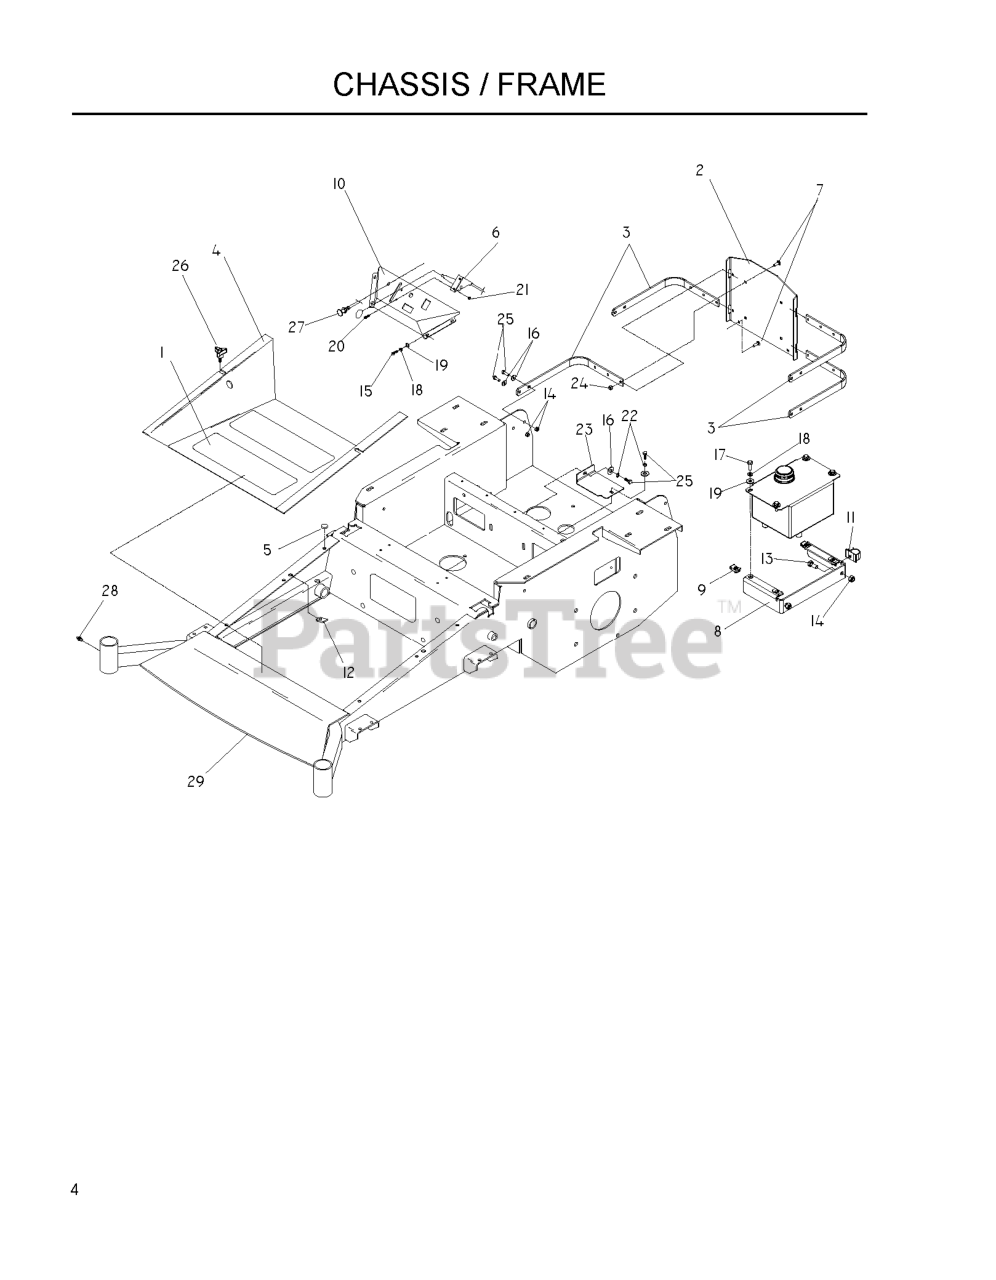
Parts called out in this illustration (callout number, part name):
1	ANTI-SKID PAD
2	XP GUARD, BLACK
3	ENGINE SHROUD BRKT
4	FOOT PLATE WIDMT
5	GROMMET, BUMPER
6	THROTTLE CONTROL W/BALL KNOB
7	BOLT 5/16C X 3/4" CARRIAGE
8	TANK MOUNT
9	1/4C - U TYPE RETAINER
10	CONSLE, ORANGE
11	PUSH-MOUNT WIRE CLIP
12	U-CLIP 5/16-18 NUT RETAINER
13	HCS 5/16C X 3/4
14	NUT 5/16 NYLOC
15	SCREW 1/4 X 5/8
16	WASHER 5/16 FLAT
17	HCS 1/4C X 3/4 HCS
18	LOCKWASHER 1/4"
19	WASHER 1/4 FLAT
20	HCS #10-24 X 1/2
21	NUT 10-24 NYLOC
22	WASHER.LOCK.HVY.HLCL.SPR.5/16
23	IDLER COVER
24	NUT 5/16C CENTERLOCK
25	HCS 5/16C X 1
26	KNOB W/STUD
27	CONTROL-CHOKE 57"
29	FRAME W/DECALS
29	FRAME W/DECALS 52/61
29	FRAME W/DECALS 72"
